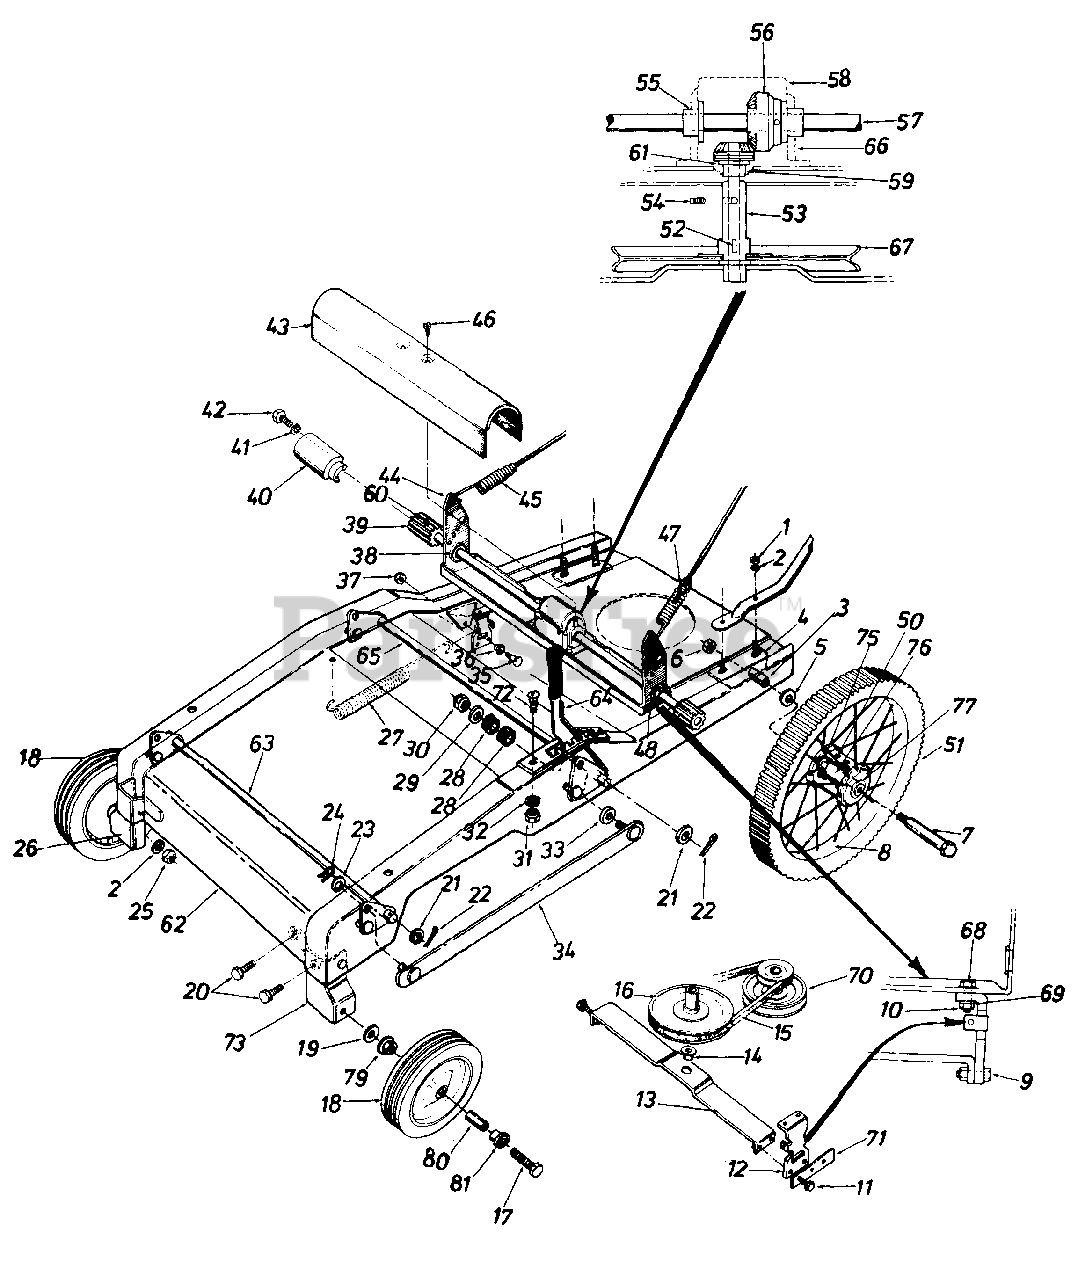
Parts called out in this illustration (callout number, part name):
1	Hex Nut 3/8-16 Thd.
2	L-Wash. 3/8" I.D.
3	Spacer - Rear Axle
4	Rear Wheel Brkt. Ass'y.
5	Fl-Wash. .53 I.D.
6	Hex Top Lock Nut 3/8-16 Thd.
7	Axle - Rear Wheel
8	Wheel Ass'y. Complete
9	Hex Sems Bolt 5/16-18 x 1.00" Lg.
10	Hex Nut 5/16-18 Thd.
11	Hex Sems Bolt 5/16-18 x 1.00" Lg.
12	Bottom Drive Frame Plate
13	Bottom Drive Frame Ass'y.
14	Flange Bearing .503 I.D.
15	3 V-Belt 28" Lg.
16	1/2 V-Pulley .50 I.D. x 6.50 O.D.
17	Hex Bolt 3/8-16 x 2.0" Lg.
18	Front Wheel Ass'y. Comp.
19	Belleville Washer
20	Hex Sems Bolt 5/16-18 x .75 Lg.
21	Fl-Wash. .53 I.D. x 1.00 O.D. x .06
22	Cotter Pin 1/8 Dia. x 1.00 Lg.
23	Fl-Wash. .53 I.D. x 1.00 O.D. x .06
24	Internal Cotter Pin 5/16" Dia.
25	Hex Nut 3/8-16 Thd.
26	Front Wheel Brkt. Ass'y. - R.H.
27	Extension Spring .56 O.D. x 8.25 Lg.
28	Rubber Washer .33 I.D. x .88 O.D. x .32
29	Fl-Wash. .40 I.D. x .88 O.D. x .06
30	Hex Ins. Jam L-Nut 3/8-24 Thd.
31	Hex Nut 5/16-18 Thd.
32	L-Wash. 5/16 I.D.
33	Fl-Wash. .40 I.D. x 1.25 O.D. x .164
34	Connecting Link Ass'y.
35	Shld. Bolt .500 Dia. x .294
36	Pivot Slide
37	Hex Ins. L-Nut 5/16-18 Thd.
38	Flange Ball Bearing .63 I.D. x 1.38 O.D. x .44
39	Drive Pinion
40	Pinion Cover
41	L-Wash. #10 I.D.
42	Hex AB-Tap Scr. #10 x .50 Lg.
43	Top Drive Frame Cover
44	Top Drive Frame
45	Extension Spring .96 O.D. x 2.12 Lg.
46	Hex AB-Tap Scr. #8 x 1/2" Lg.
47	Hex Elastic Stop Nut 1/4-20 Thd.
48	Collar 5/8 I.D.
51	Tire Only 16 x 1.75
52	#2 Woodruff Key
53	Pinion Ass'y.
54	Set Screw 5/16-18 x .25 Cup
55	Flange Bearing .630 I.D.
56	Bevel Gear
57	Drive Shaft
58	Gear Box Cover
59	Flange Bearing 1/2" Dia.
60	Roll Pin 3/16 Dia. x 1.0 Lg.
62	26" Deck
63	Lift Bracket Shaft Ass'y.
64	Lift Handle
65	Lift Bracket Shaft Ass'y.
66	Gear Box
67	1/2 V-Pulley .50 I.D. x 6.50 O.D.
68	Hex Sems Bolt 5/16-18 x .75 Lg.
69	L-Wash. 5/16" I.D.
70	Two-Step Engine Pulley
71	Stop-Drive Frame
72	Carriage Bolt 5/16-18 x .62 Lg.
73	Front Wheel Brkt. Assembly - L.H.
75	Flange Ball Brg. .63 I.D. x 1.38 O.D. x .44
76	Wheel Spacer
77	Flange Ball Brg. .63 I.D. x 1.38 O.D. x .44
79	Ball Bearing 1/2" I.D.
81	Ball Bearing 3/8" I.D.
